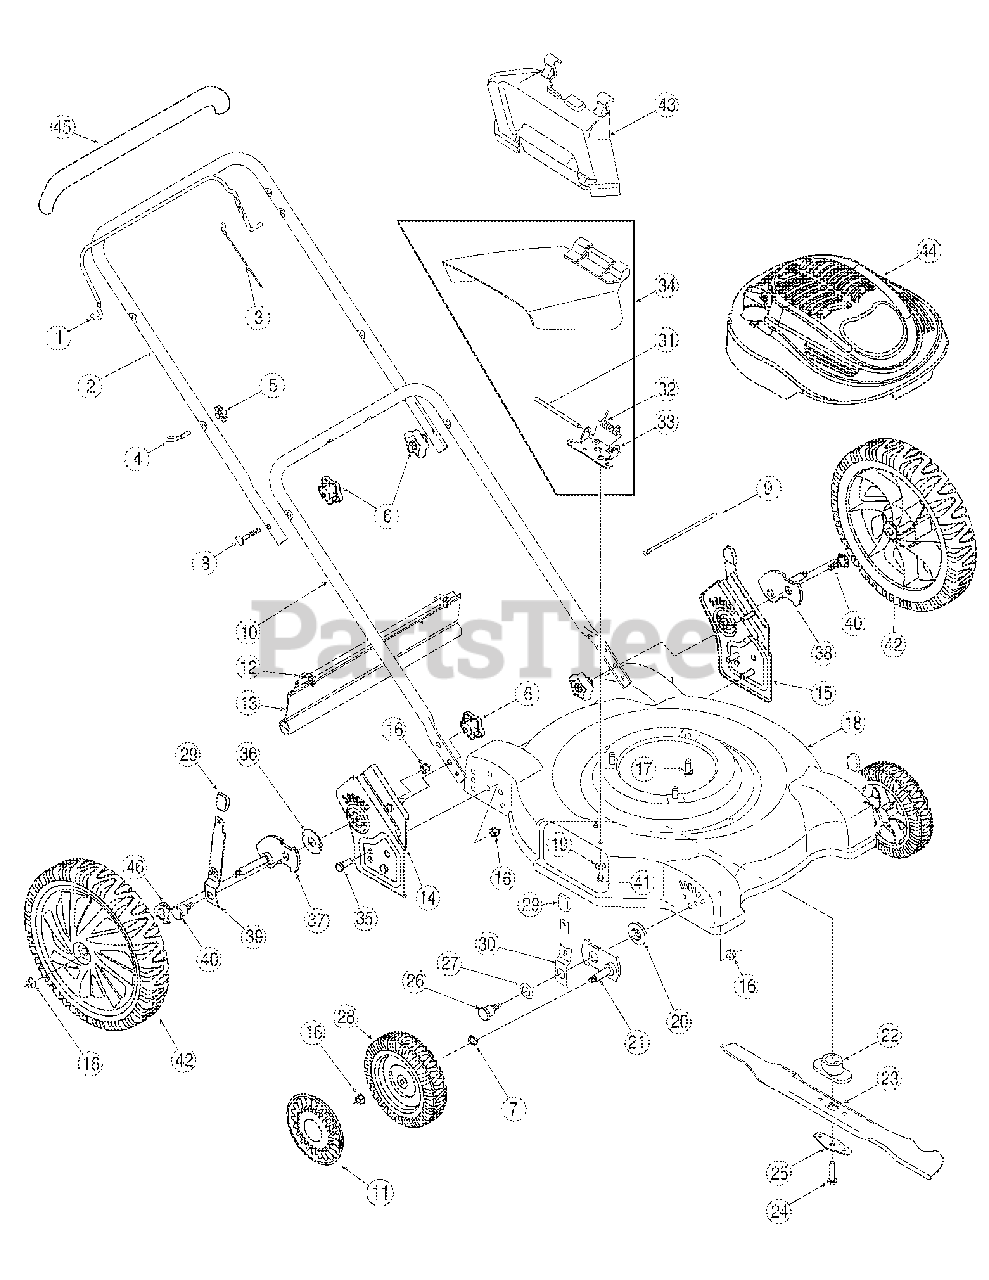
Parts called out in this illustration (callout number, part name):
3	Blade Control Cable - 48.25"
6	Wing Nut
7	Wave Washer, .510 x .750 x .017
8	Carriage Bolt 5/16-18 x 2.0
11	Hub Cap
12	Hinge Clip
13	Trail Shield
17	Hex Washer Screw 3/8-16 x 1.0
19	Bell Washer.265 x.75
20	Height Adjuster Bearing
21	Pivot Arm Assembly
22	Blade Adapter, 1/4 inch keyway
22	Blade Adapter, 3/16 inch keyway
23	22" Mulching Blade
24	Hex Cap Screw 3/8-24 x 1.5
25	Blade Bell Support
26	Shoulder Screw 3/8 - 16 x .302
27	Bell Washer.760 ID x 1.25 OD
28	Front Wheel Assembly 7 x 2.125
29	Height Adjuster Knob
30	Front Spring Lever
31	Hinge Pin
32	Torsion Spring
33	Deflector Chute Adapter
34	Side Discharge Chute Assembly
35	Hex Cap Screw 3/8-16 x .75
36	Thrust Bearing.688 ID x 1.94 OD
37	Rear Pivot Arm Assembly RH
38	Rear Pivot Arm Assembly LH
39	Rear Spring Lever
40	Shoulder Screw 3/8 - 16 x .442
41	Screw 1/4-20 x.50
42	Rear Wheel Assembly 12 X 2.125
43	Mulching Baffle
44	Engine Shroud
45	Deluxe Bail Cover
46	Spring Washer,.500 x 1.00 X .022
